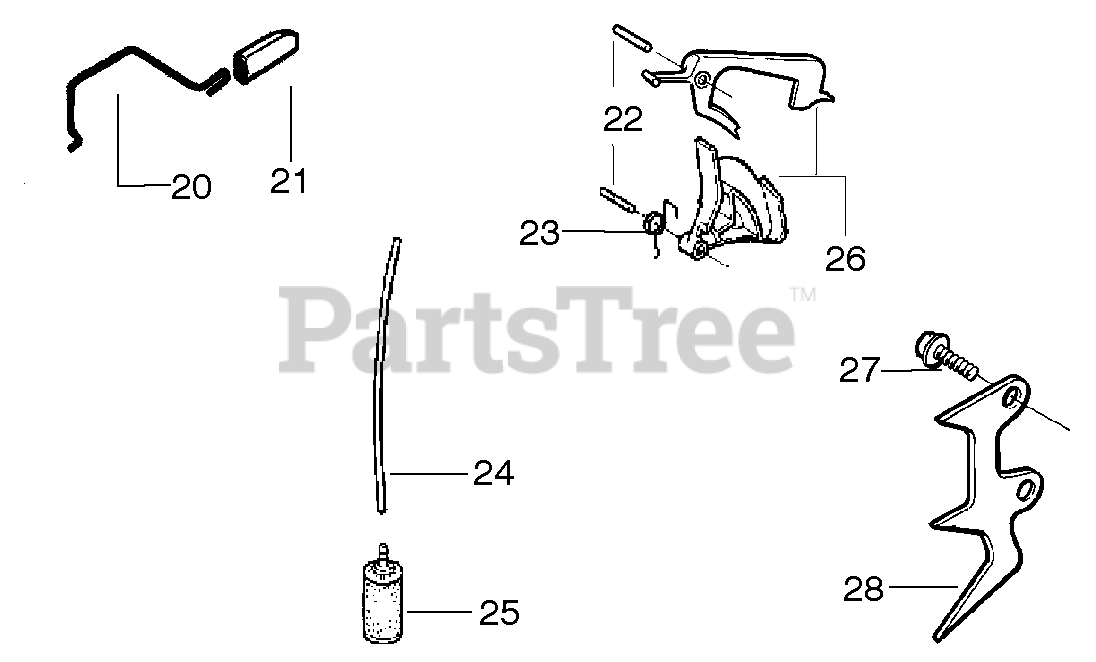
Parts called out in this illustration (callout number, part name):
20	Wire - Throttle
21	Cap - Wire
24	Kit - Fuel line
25	Assy. Fuel Pickup
26	Kit - Throttle Trigger
28	Assy. Spike
